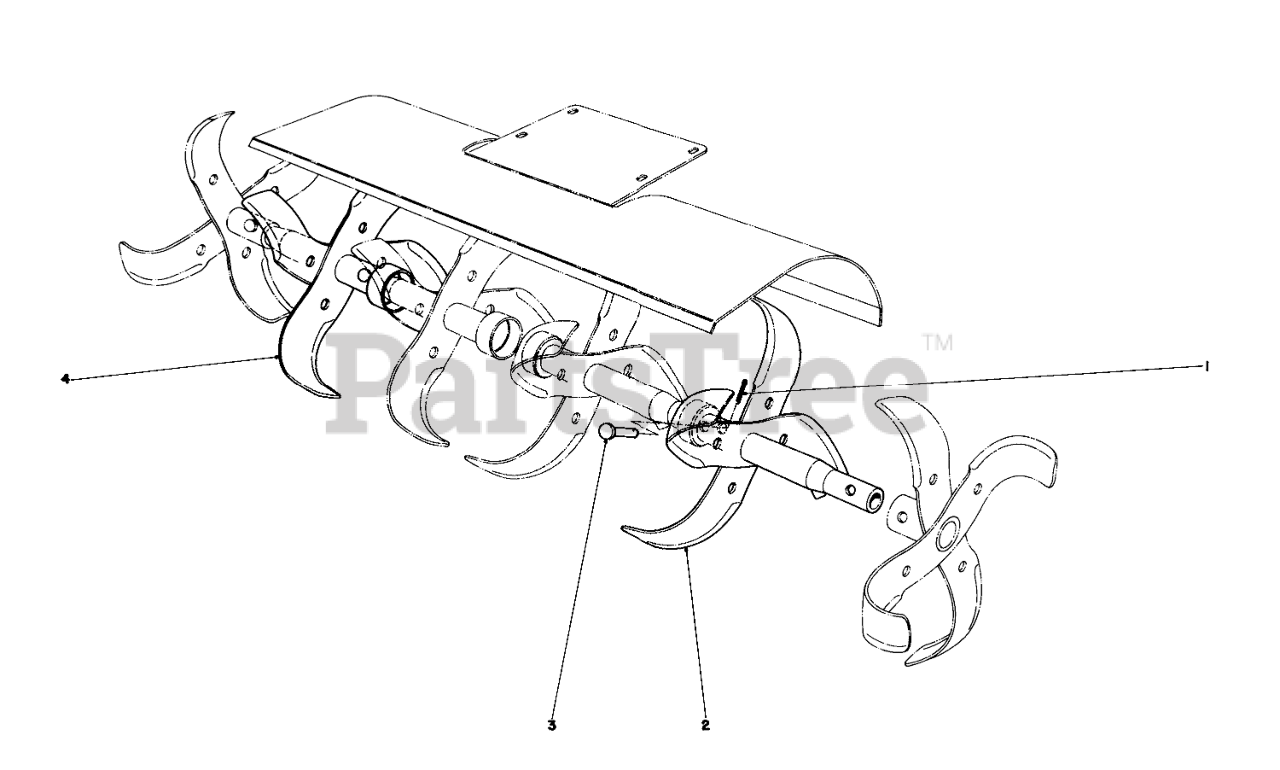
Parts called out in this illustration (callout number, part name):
1	PIN-COTTER
2	Inner Tine L.H.
3	TINE PIN
4	Inner Tine R.H.
